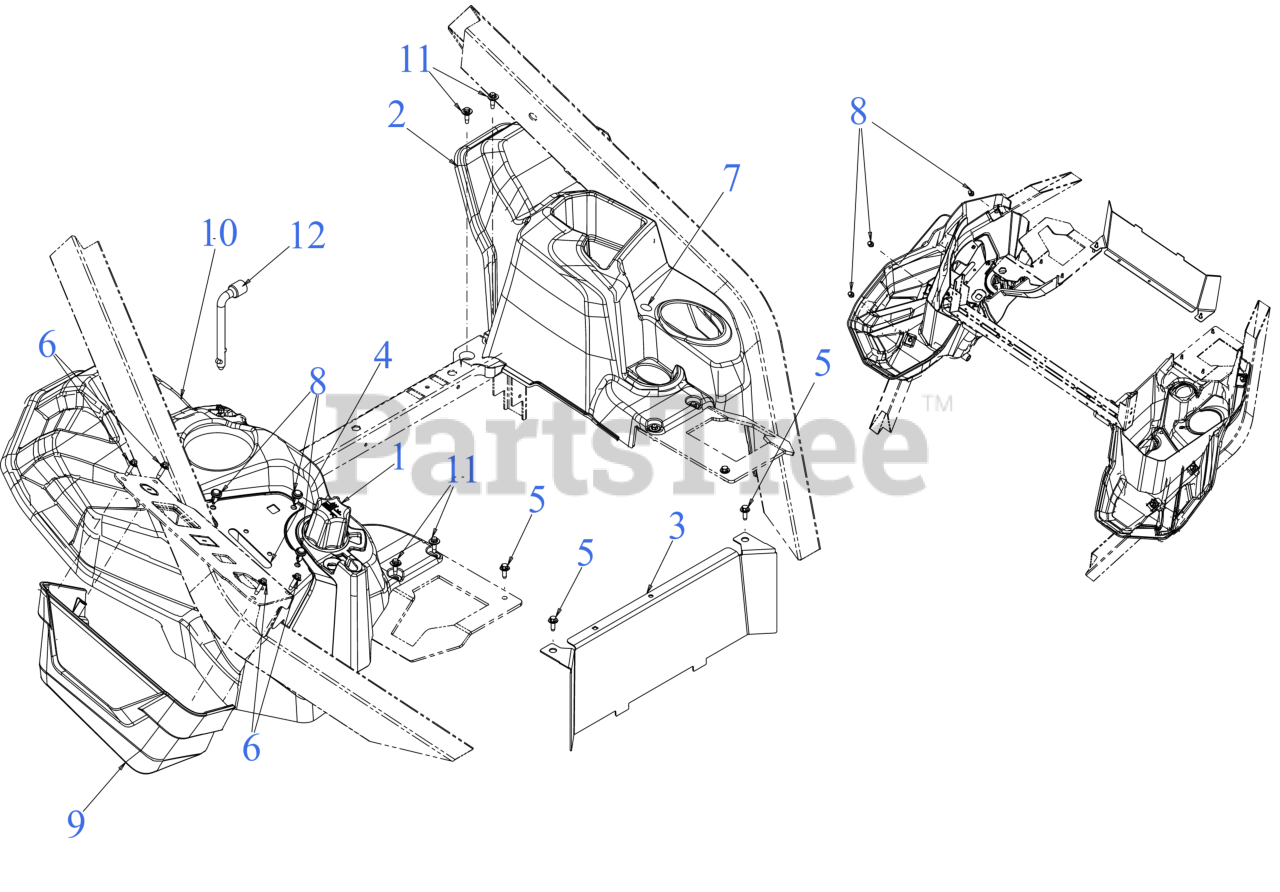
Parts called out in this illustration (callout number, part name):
1	DECK HEIGHT ADJUSTMENT KNOB
2	CONSOLE (LH)
3	SEAT BOX FRONT PLATE
4	THROTTLE COVER PLATE
5	SCREW M6-1 x .625
6	SCREW 1/4-10 x .750
7	RATCHET CLIP
8	PLASTIC RIVET
9	CONTROL PANEL CONSOLE
10	CONSOLE (RH)
11	SHOULDER SCREW M6-1 .368 X.115
12	MULTI TOOL 1/2" SOCKET
